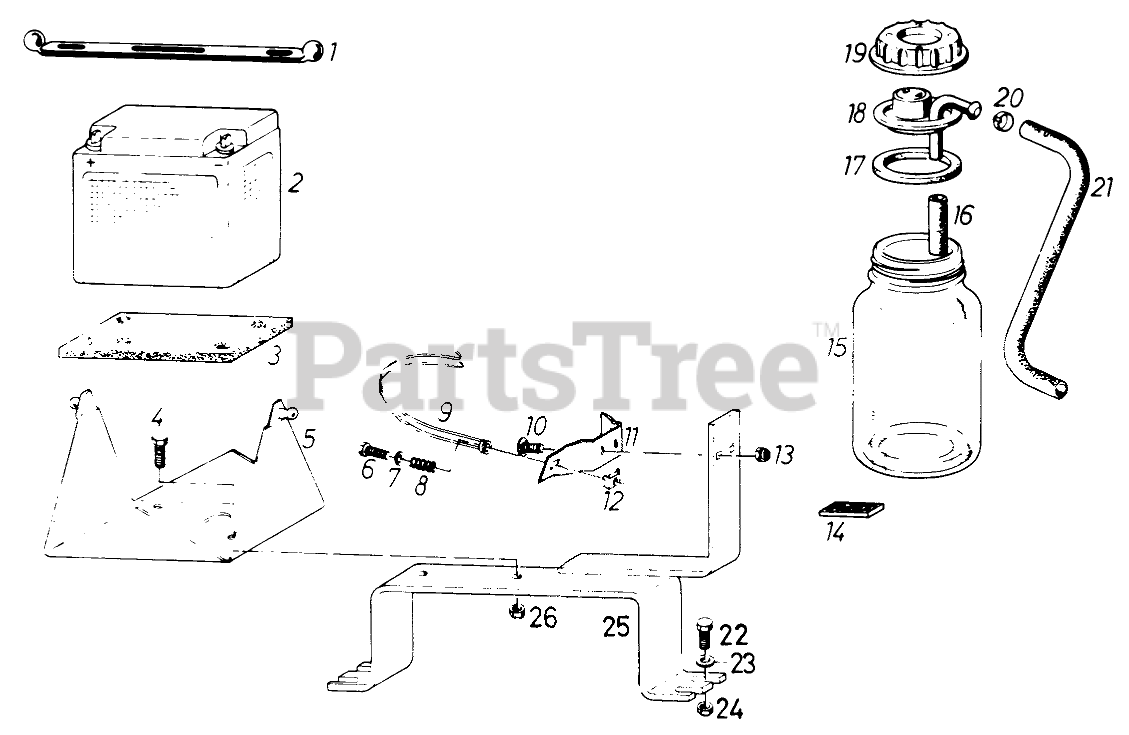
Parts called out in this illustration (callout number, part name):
1	Tension Strap
3	Plate
5	Battery Support
6	Screw
7	Washer
8	Spring
9	Clamp
10	Screw
11	Clamp
12	Cage Nut
15	Compensating Tank
17	Gasket
18	Valve
19	Cover
20	Clamp
23	Washer
25	Support Assy.
